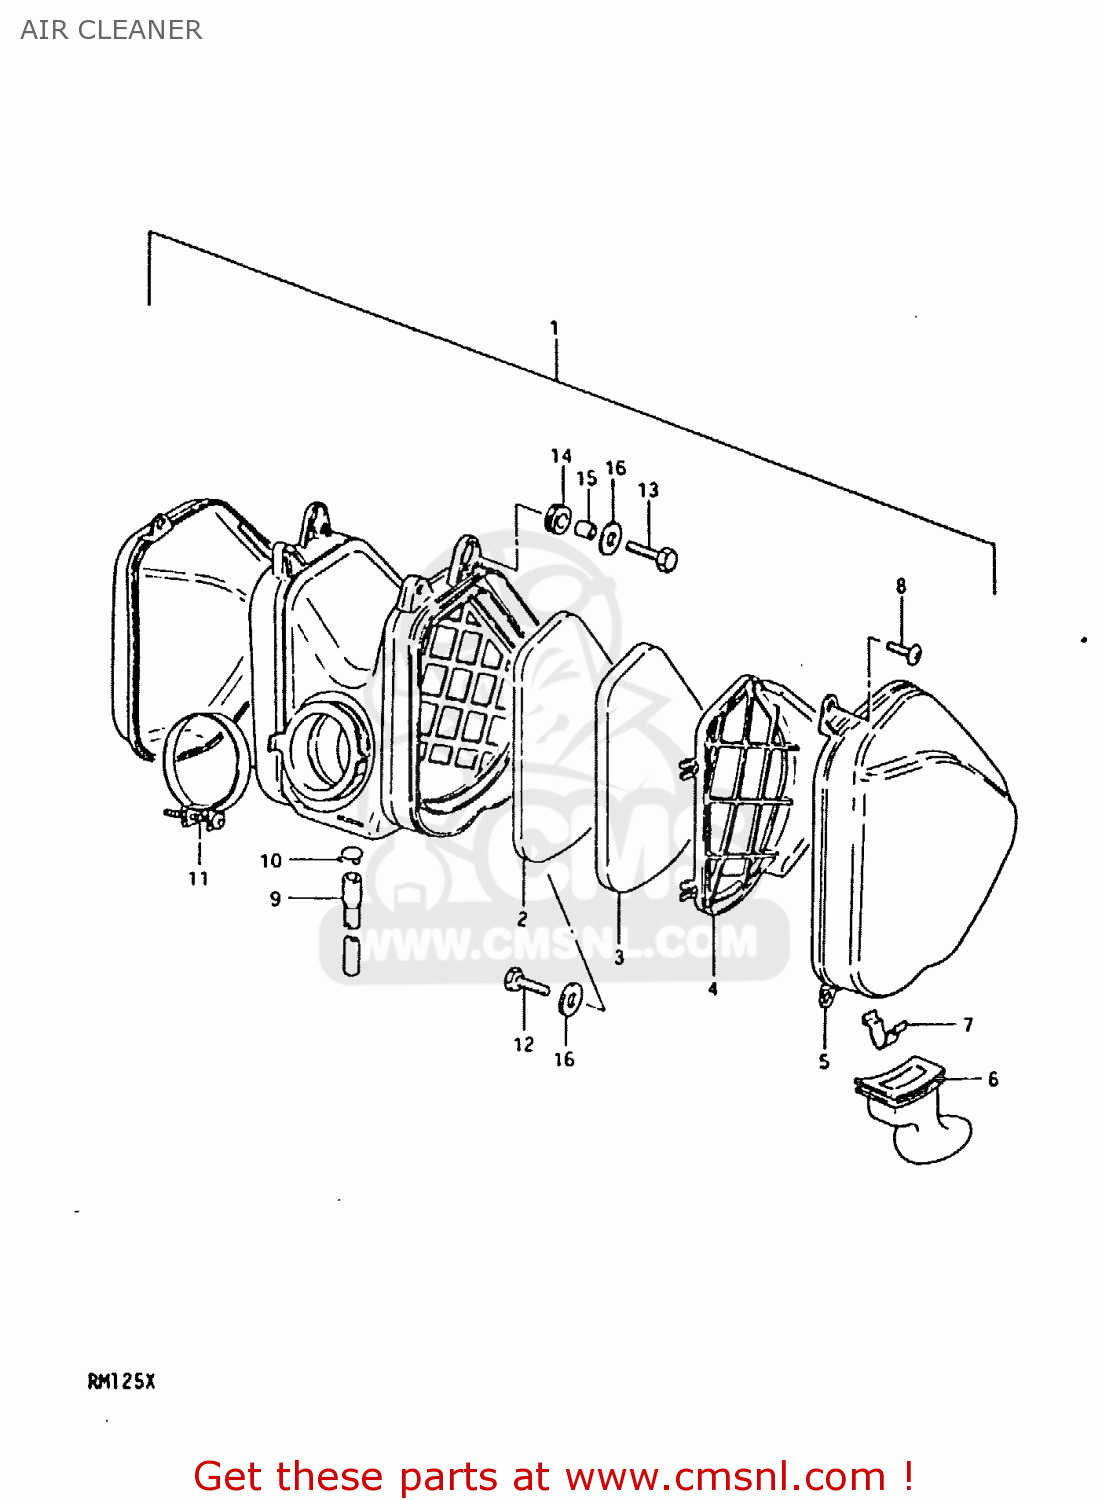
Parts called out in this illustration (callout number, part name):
1	CLEANER ASSEMBLY,AIR
2	FILTER,L
3	FILTER,2ND,R
4	HOLDER,FILTER
5	CAP,AIR CLEANER
6	DRAIN TUBE
7	DRAIN STOPPER
8	SCREW
9	DRAIN TUBE
10	CLIP
11	CLAMP
12	BOLT, UPPER
13	BOLT
14	CUSHION
15	SPACER (7X9X7)
16	WASHER
